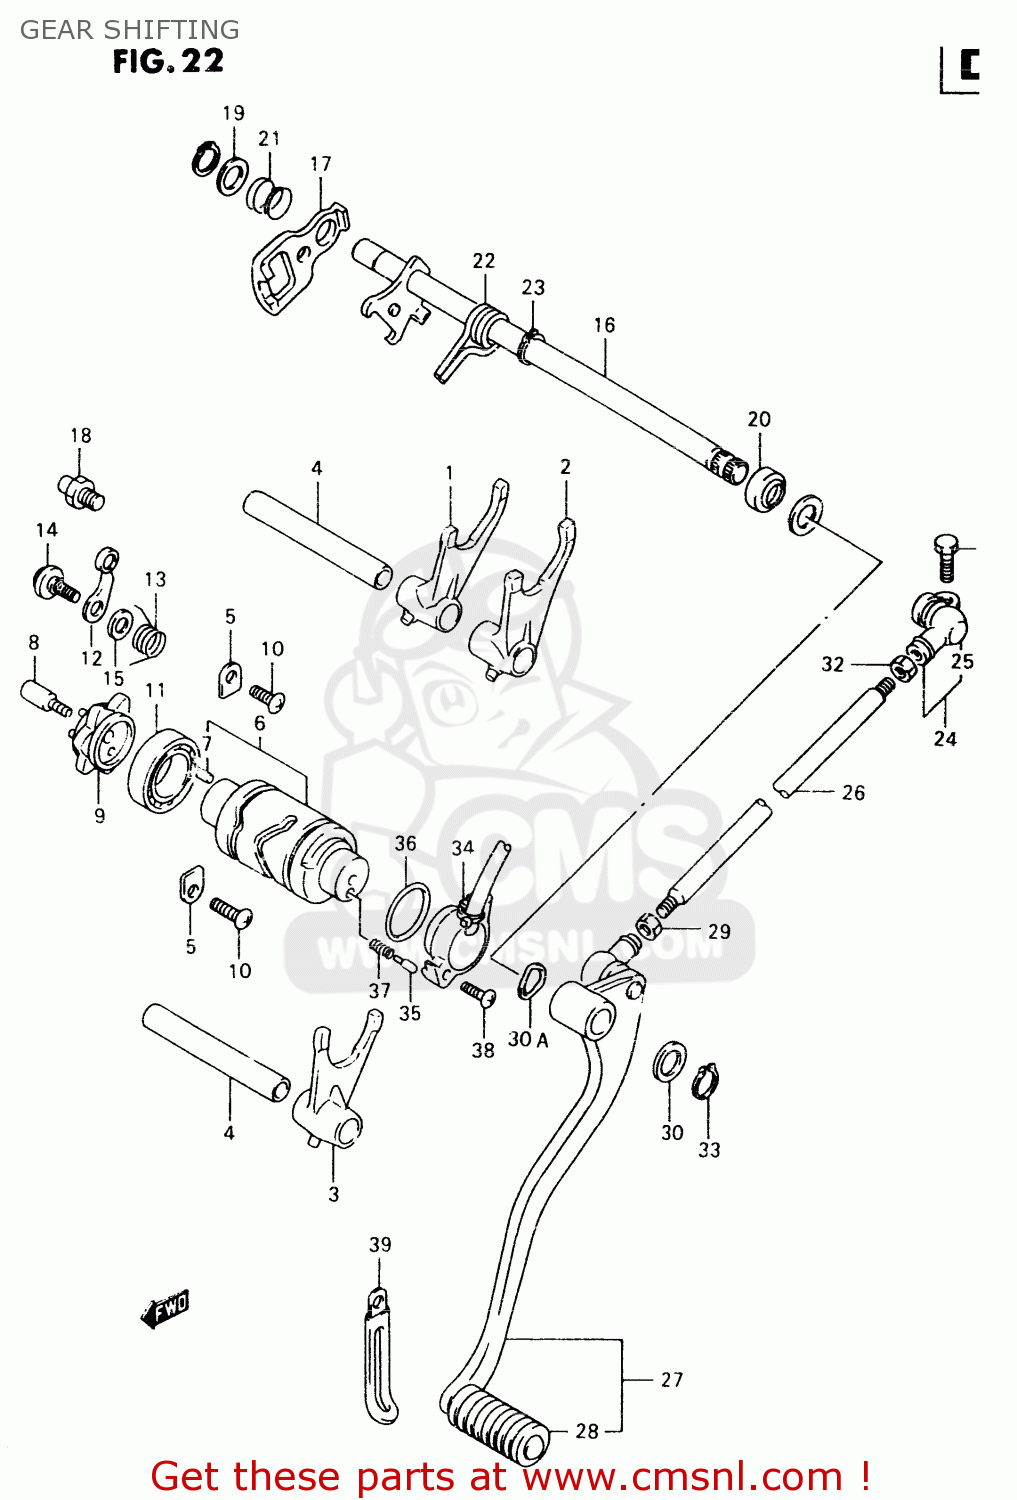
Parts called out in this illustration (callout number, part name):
1	FORK,GEAR SHIFT NO.1
2	FORK,GEAR SHIFT NO.2
3	FORK,GEAR SHIFT NO.3
4	SHAFT,GEAR SHIFT FORK NO.1
5	RETAINER
6	CAM,GEAR SHIFT
7	PIN
8	PIN,SHIFT CAM DRIVEN GEAR
9	PLATE,GEAR SHIFT CAM
10	SCREW
11	BEARING
12	STOPPER,GEAR SHIFT CAM
13	SPRING,SHIFT CAM STOPPER
14	BOLT(6X14.3)
15	WASHER
16	SHAFT,GEAR SHIFT
17	PLATE,GEAR SHIFT CAM D
18	STOPPER,GEAR SHIFT CAM
19	SHIM(14X22X1)
20	SEAL,OIL(14X22X6)
21	SPRING
22	SPRING
23	CIRCLIP
24	ARM,GEAR SHIFT SHAFT
25	COVER,DUST
26	ROD,GEAR SHIFT LINK
27	LEVER ASSY,GEAR SHIFT
28	RUBBER,GEAR SHIFT PEDAL
29	NUT
30	WASHER(12.5X20X1)
30A	WASHER
31	BOLT
32	NUT
33	CIRCLIP,12 MM
34	BASE ASSY,GEAR SHIFT TERMINAL
35	PIN(5X15.5)
36	O RING(D:2.4,ID:25.7)
37	SPRING
38	SCREW
39	CLAMP L:62
